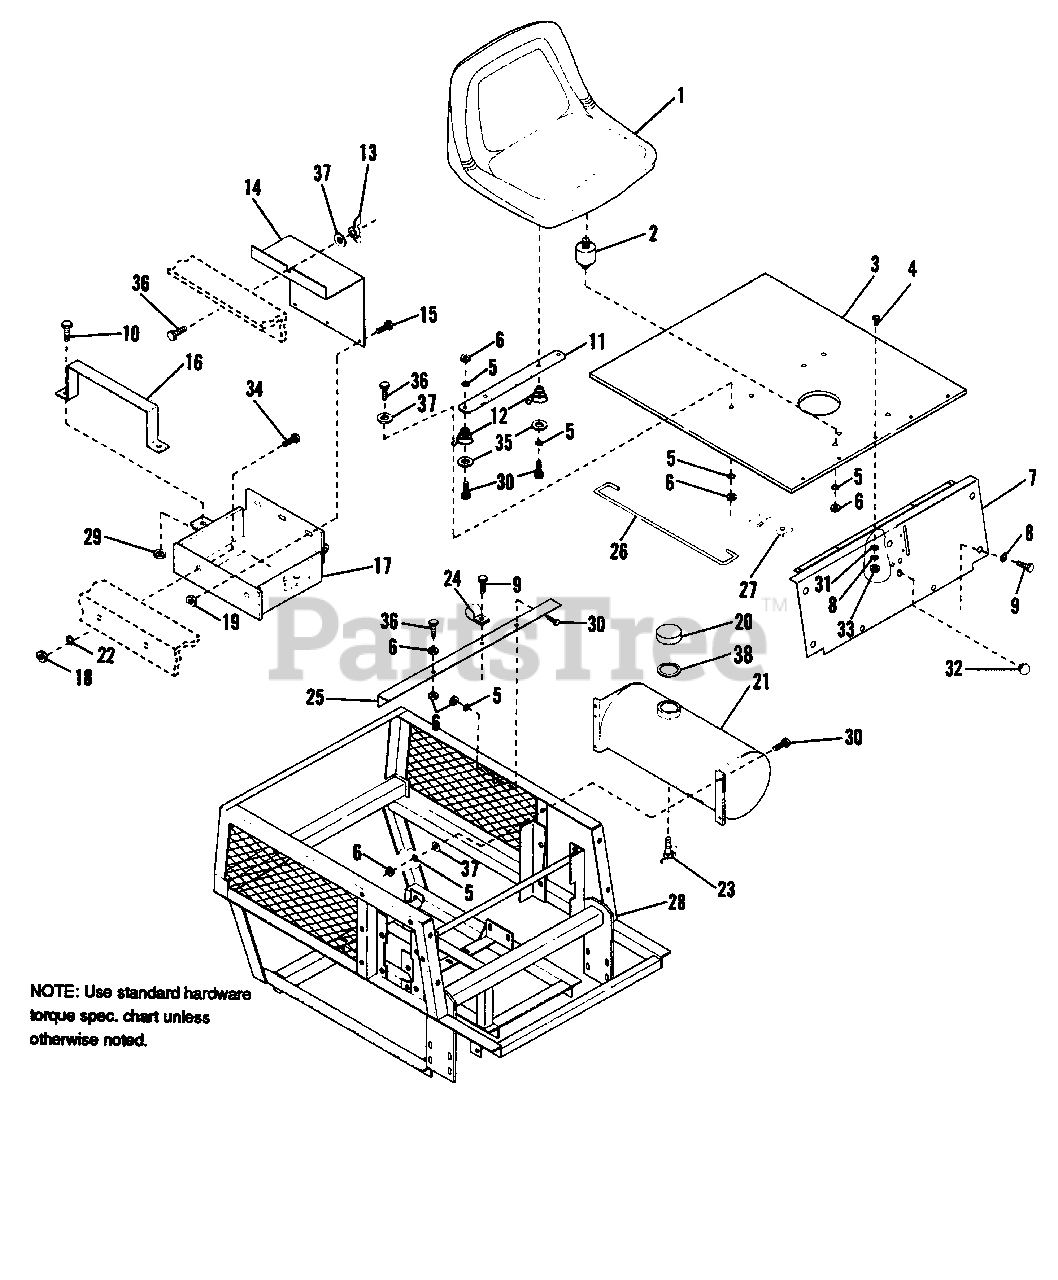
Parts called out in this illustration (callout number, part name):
3	SEAT PAN ASSY.
4	SCREW, Pan Head Phillips, #10-24 x 1
5	LOCKWASHER, Spring 5/16
6	NUT, Hex 5/16-18
7	FRONT ASSY.
8	LOCKWASHER, Spring #10
9	SCREW, Taptite 1/4-20 x 5/8
10	CAPSCREW, Hex 5/16-18 x 2-1/2
11	BAR, Spring
12	SPRING, Seat
13	WINGNUT 5/16-18
14	COVER, Battery
15	SCREW, Round Head #10-32 x 3/8
16	STRAP, Battery
17	BATTERY BOX ASSY.
18	NUT, Hex 3/8-16
19	LOCKNUT, Hex #10-32
20	CAP, Fuel Tank
21	FUEL TANK ASSY.
22	LOCKWASHER, Spring 3/8
23	VALVE, Shutoff
25	SUPPORT, Seat
26	ROD, Support
27	BRACKET, Latch
28	FRAME ASSY., (1691841, 1691843, 1691845)
28	FRAME ASSY., (1691842, 1691844, 1691846)
29	NUT, Hex, Centerlock 5/16-18
30	CAPSCREW, Hex 5/16-18 x 1
31	WASHER, Plain
32	HOLE PLUG, (1691841, 1691843, 1691845 only)
33	NUT, Hex #10-24
34	CAPSCREW, Hex 3/8-16 x 1
35	WASHER, Plain
36	CAPSCREW, Hex 5/16-18 x 3/4
37	WASHER, Plain
